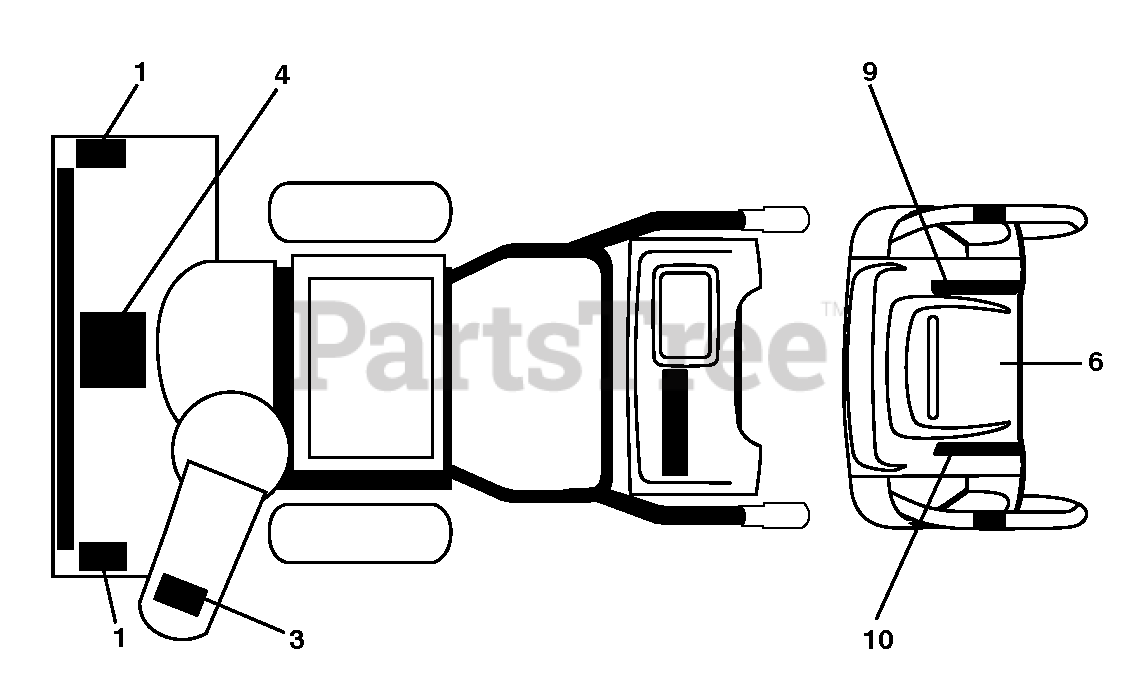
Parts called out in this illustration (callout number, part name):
1	DECAL.SNOWTHR.AUGER
3	DECAL.SNOWTR.READ.OWN.MAN.E/F
4	DECAL.SNOWTR.READ.OWN.MAN.E/F
6	DECAL.CONSOLE.SNOW.INST.ENG/FR
9	DECAL.CONS.RH.INST.GRY
10	DECAL.CONS.LH.REMOTE.INST.GRY
